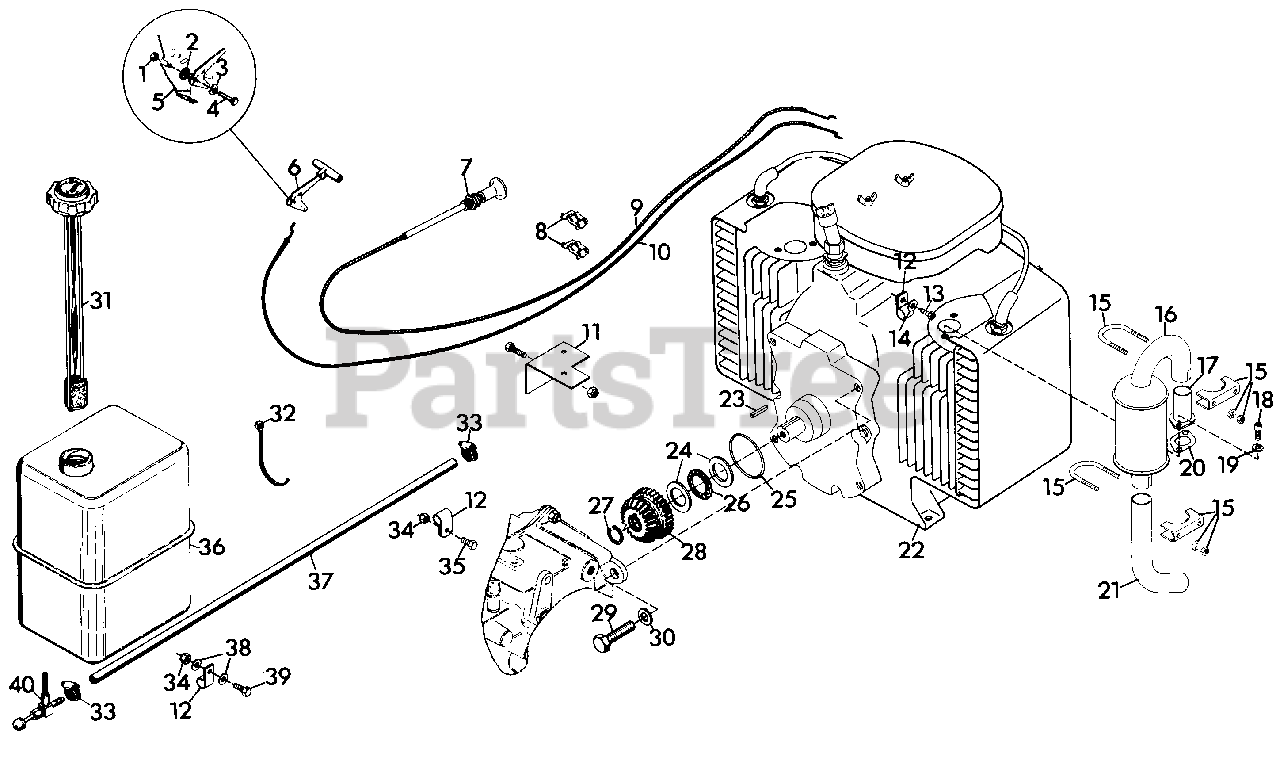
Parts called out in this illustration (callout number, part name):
1	NUT, LOCK 1/4-28
2	WASHER, FRICTION
3	WASHER, SPRING
4	BOLT, HEX 1/4-28X.75
5	BRACKET, MOUNTING
6	ASSEMBLY, KNOB AND LEVER
7	NUT, JAM 3/8-24 HEX
8	CLIP, SPEED
9	CONTROL, CHOKE
10	ASSEMBLY, CHOKE CONDUIT
11	BRACKET, THROTTLE AND CHOKE
12	CLAMP, NYLON
13	SCREW, TAPPING 1/4-20X.625 HHD ST
14	WASHER, FLAT .281X.625X.065
15	CLAMP, MUFFLER
16	MUFFLER
17	WELDMENT, HEADER
18	SCREW, CAP 5/16-18X.75 S/HD
19	WASHER, LOCK 5/16-18 REG.
20	GASKET, EXHAUST
21	EXTENSION, EXHAUST
22	ENGINE, 16 HP MAGNUM
23	KEY, SQUARE .250X1.250
24	RACE, BEARING THRUST 1.125X1.750X.123/.126
25	O-RING, 3.000X3.188X.094
26	BEARING, THRUST 1.127X1.740X.078
27	RING, RETAINING 1.125 SHAFT
28	GEAR, SPUR AND BEVEL, INPUT
29	BOLT, HEX 1/2-13X1.75
30	WASHER, LOCK 1/2 REG.
31	GAUGE, GAS
32	TIE, CABLE
33	CLAMP, HOSE
34	NUT, LOCK 5/16-18
35	BOLT, HEX 5/16-18X.75
36	TANK, FUEL
37	LINE, FUEL
38	WASHER, FLAT .344X.688X.065
39	BOLT, HEX 5/16-18X1.00
40	VALVE, FUEL 90 DEG. REVERSE FLOW
NS	NUT, LOCK 10-32
NS	SCREW, MACHINE 10-32X.50 PHD
